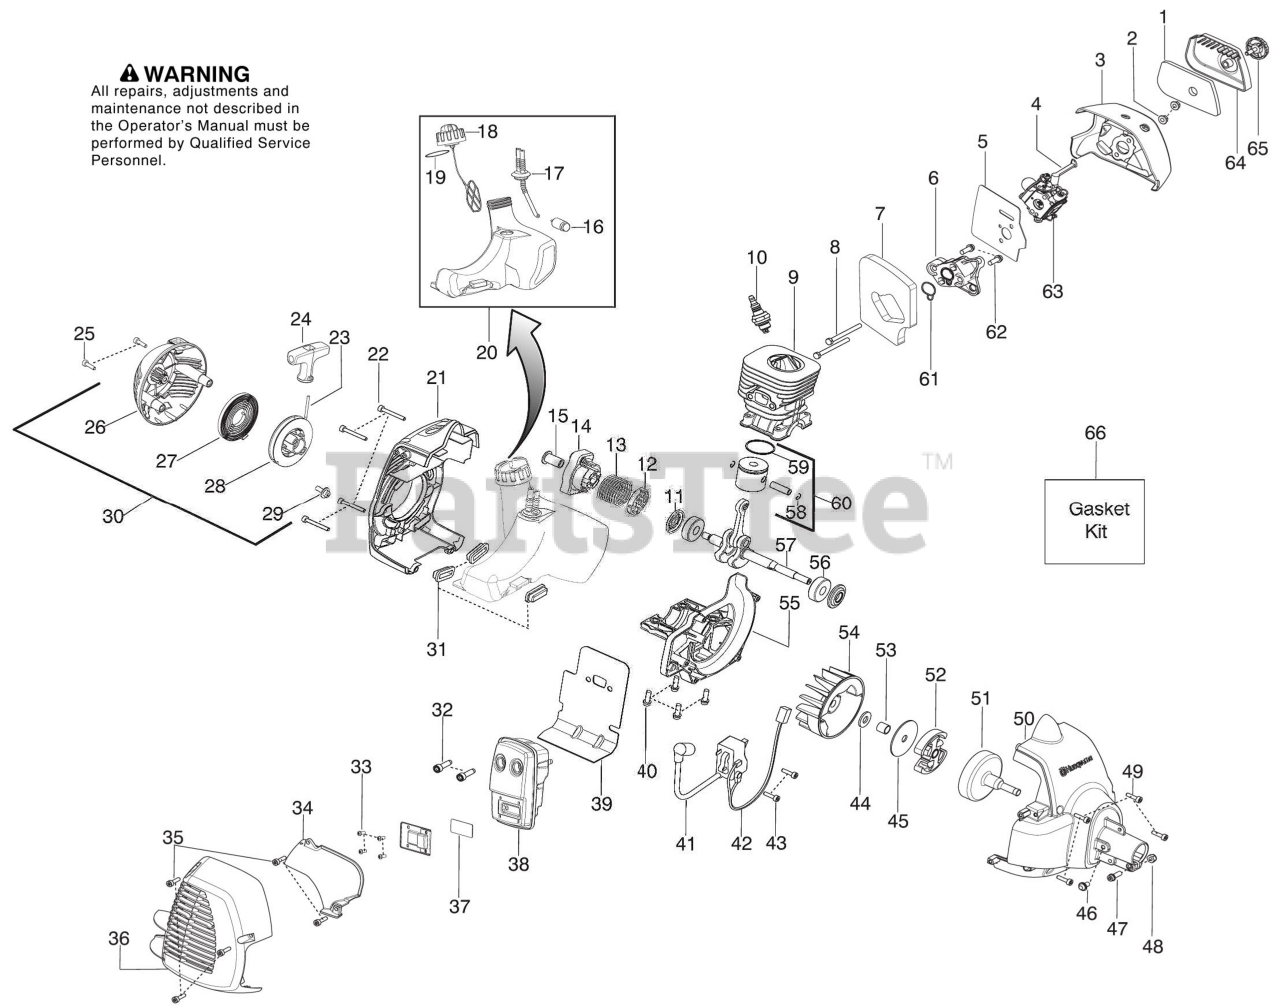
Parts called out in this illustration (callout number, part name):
2	Nut-Carb. Screw
3	Air Box
4	Lever - Choke
5	Kit-Carb. Gasket
6	Adaptor-Carb.
7	Kit-Gasket
9	Cylinder
10	Plug-Spark (RCJ-6Y)
11	Kit-Crankshaft seal
12	Washer-Starter
13	Spring-Starter Cup
14	Assy-Starter Cup
15	Coupling-Starter
16	Assy-Fuel Filter
17	Kit-Fuel Line
18	Assy-Cap w/ret.
19	Kit - Gasket
20	Assy-Fuel Tank
21	Shroud-Rear
24	Handle-Starter
26	Starter Hsg. w/eyelet
27	Kit-Starter Spring
28	Kit-Starter Pulley
30	Assy-Starter Hsg.
31	Isolator-Tank
32	Bolt-Muffler
34	Shield-Heat
36	Guard-Muffler
37	Kit-Spark Arrestor
38	Assy-Muffler
39	Gasket-Paper Metal
41	Module
42	Assy-Leadwire
45	Washer-Clutch
50	Assy-Fan Housing
51	Assy-Clutch Drum
52	Kit-Clutch Assy.
57	Kit-Crankshaft
58	Retainer-Piston Pin
59	Ring-Piston
60	Kit-Piston
61	Kit-Gasket
62	Screw
63	Kit-Carb.
64	Cover-Air Box
66	Kit-Gasket
